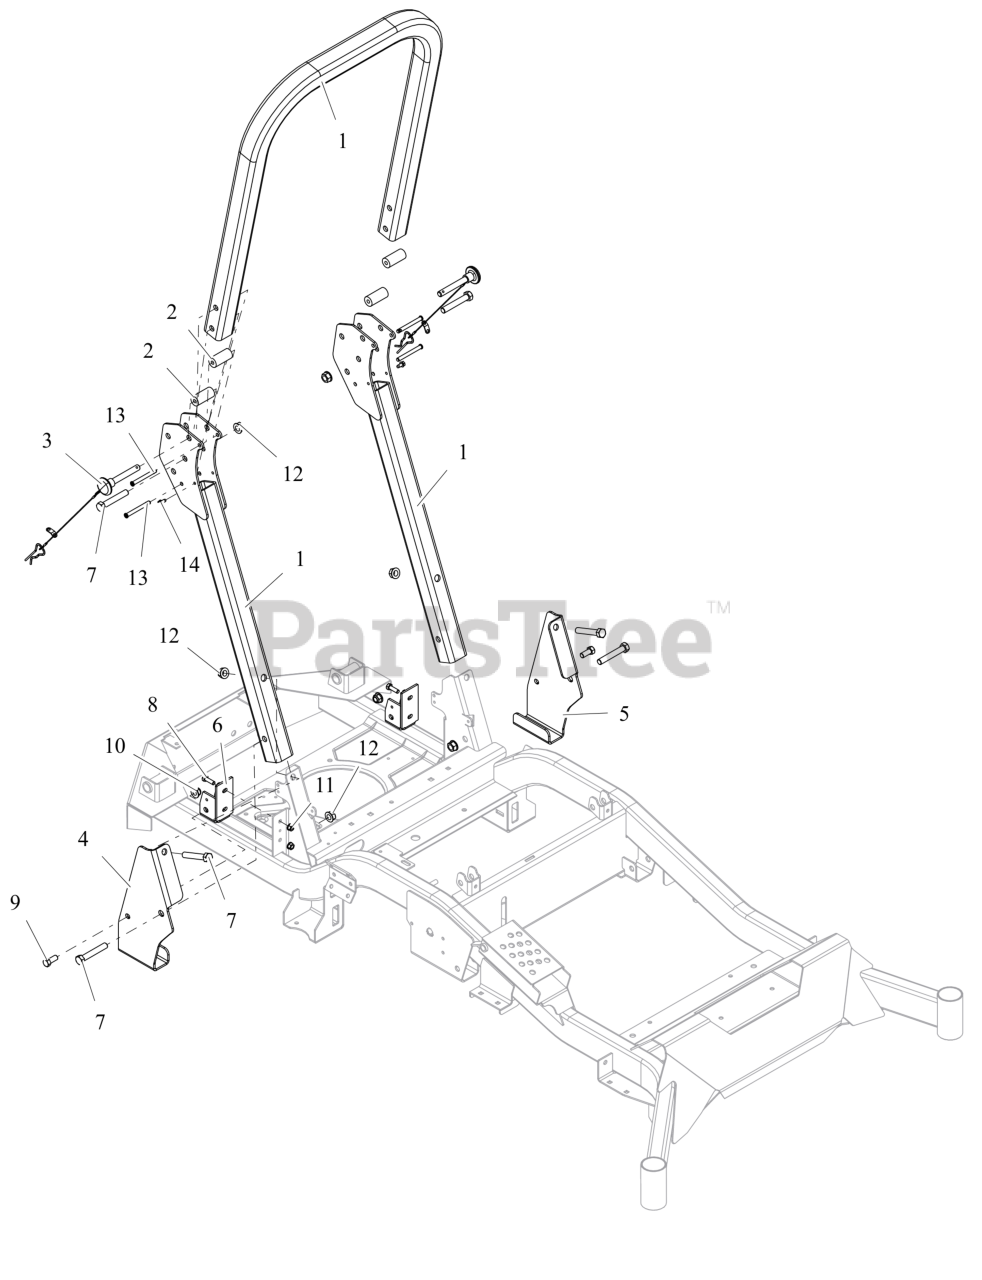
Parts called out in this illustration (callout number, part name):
1	ROPS, REPLACEMENT
2	BUMPER, ROPS ANTI-VIBRATION
3	PIN, ROPS W/LANYARD
4	BRKT, ROPS SUPPORT - RH
5	BRKT, ROPS SUPPORT -LH
6	BRKT, ROPS SUPPORT (BLACK)
7	BLT, HEX .50-13X3.00 G5 ZCC
8	BLT, HEX .31-18X1.00 G8 ZCC
9	BLT, HEX .44-14X1.00 G5 ZCC
10	NUT, LK-NYL-FLG .44-14 GR5 ZC120
11	NUT,LK-CTR-FLG .31-18 GF ZCC
12	NUT-LK-CTR-FLG .500-13 GG ZCC
13	PIN, SLIC .312 X 2.57
14	SCR-TAP .25-20X.50 HWH ZCC
